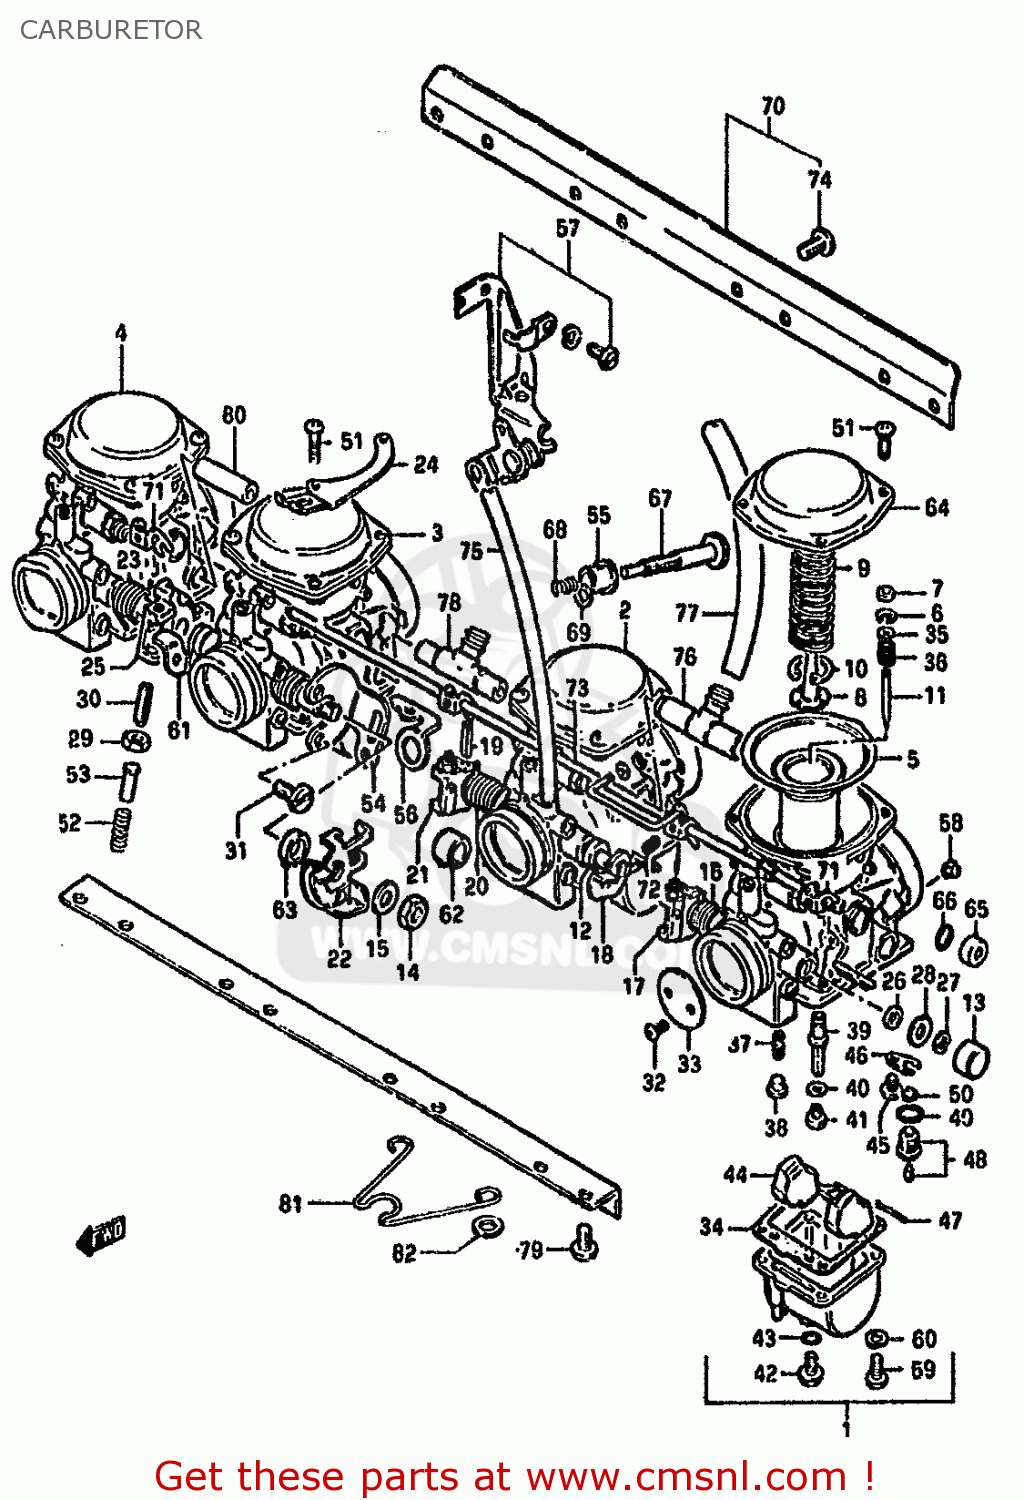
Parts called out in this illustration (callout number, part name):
1	CARBURETOR, LH
2	CARBURETOR, ML
3	CARBURETOR, MR
4	CARBURETOR, RH
5	DIAPHRAGM,CARBURETOR
6	CLIP,NEEDLE
7	RING
8	HOLDER,GUIDE
9	SPRING
10	E RING
11	NEEDLE, JET (5057-2)
12	GASKET
13	CAP
14	NUT 8MM
15	WASHER
16	SPRING,THROTTLE SHAFT
17	SHAFT,THROTTLE
18	SHAFT ASSEMBLY
19	PIN,THROTTLE SHAFT
20	SPRING,THROTTLE SHAFT
21	LEVER,THROTTLE SHAFT
22	LEVER ASSEMBLY,THROTTLE
23	SPRING,THROTTLE SHAFT
24	BRACKET,THROTTLE CABLE
25	SHAFT,THROTTLE
26	SEAL
27	E RING
28	GASKET,THROTTLE SHAFT (NAS)
29	NUT
30	SCREW
31	SCREW
32	SCREW
33	VALVE,THROTTLE (BUTTERFLY)
34	GASKET,FLOAT CHAMBER (NAS)
35	WASHER
36	SPRING
37	JET, PILOT (42.5)
38	PLUG,NEEDLE JET
39	JET, NEEDLE (X-2)
40	WASHER,NEEDLE NOZZLE
41	JET, MAIN (112.5)
42	PLUG,DRAIN
43	GASKET (NAS)
44	FLOAT
45	SCREW 4X6
46	PLATE,NEEDLE VALVE FITING
47	PIN,FLOAT
48	VALVE ASSEMBLY,NEEDLE
49	O-RING,NEEDLE VALVE
50	FILTER
51	SCREW
52	SPRING,THROTTLE SCREW
53	PIN,THROTTLE LEVER
54	BRACKET,THROTTLE ADJUST
55	BUSH
56	BRACKET,THROTTLE ADJUST
57	BRACKET ASSY
58	JET,AIR
59	SCREW
60	LOCK WASHER
61	SHAFT,THROTTLE
62	RING
63	RING
64	COVER,DIAPHRAGM
65	CAP,STARTER VALVE
66	O RING
67	SCREW
68	SPRING
69	WASHER
70	FLANGE ASSY
71	LEVER
72	SCREW
73	SHAFT,STARTER
74	SCREW
75	HOSE
76	NIPPLE
77	HOSE,CARBURETOR
78	NIPPLE
79	SCREW
80	NIPPLE
81	CLIP
82	WASHER
